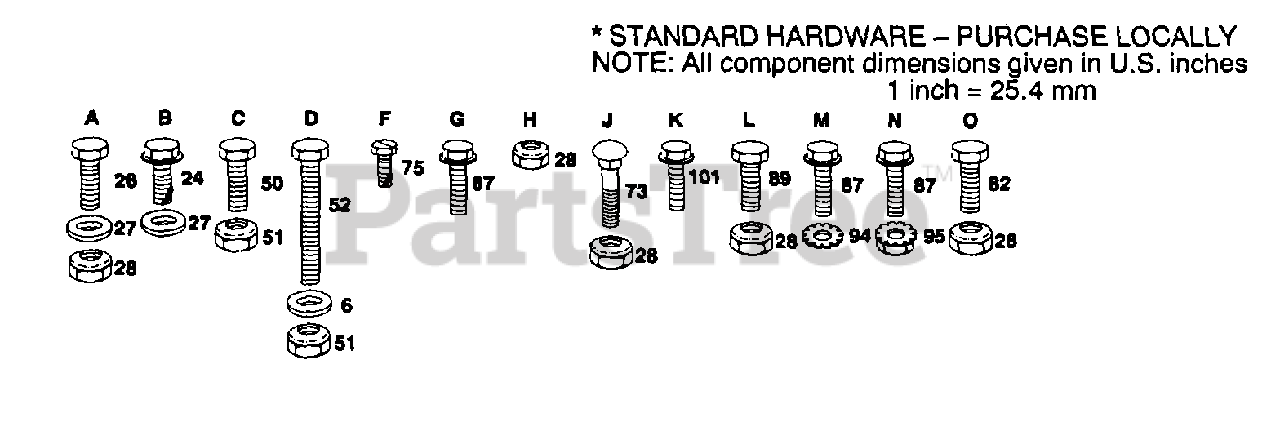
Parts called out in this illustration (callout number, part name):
26	WASHER
27	SPRING H
51	NUT
52	SPRING.RETAINER
